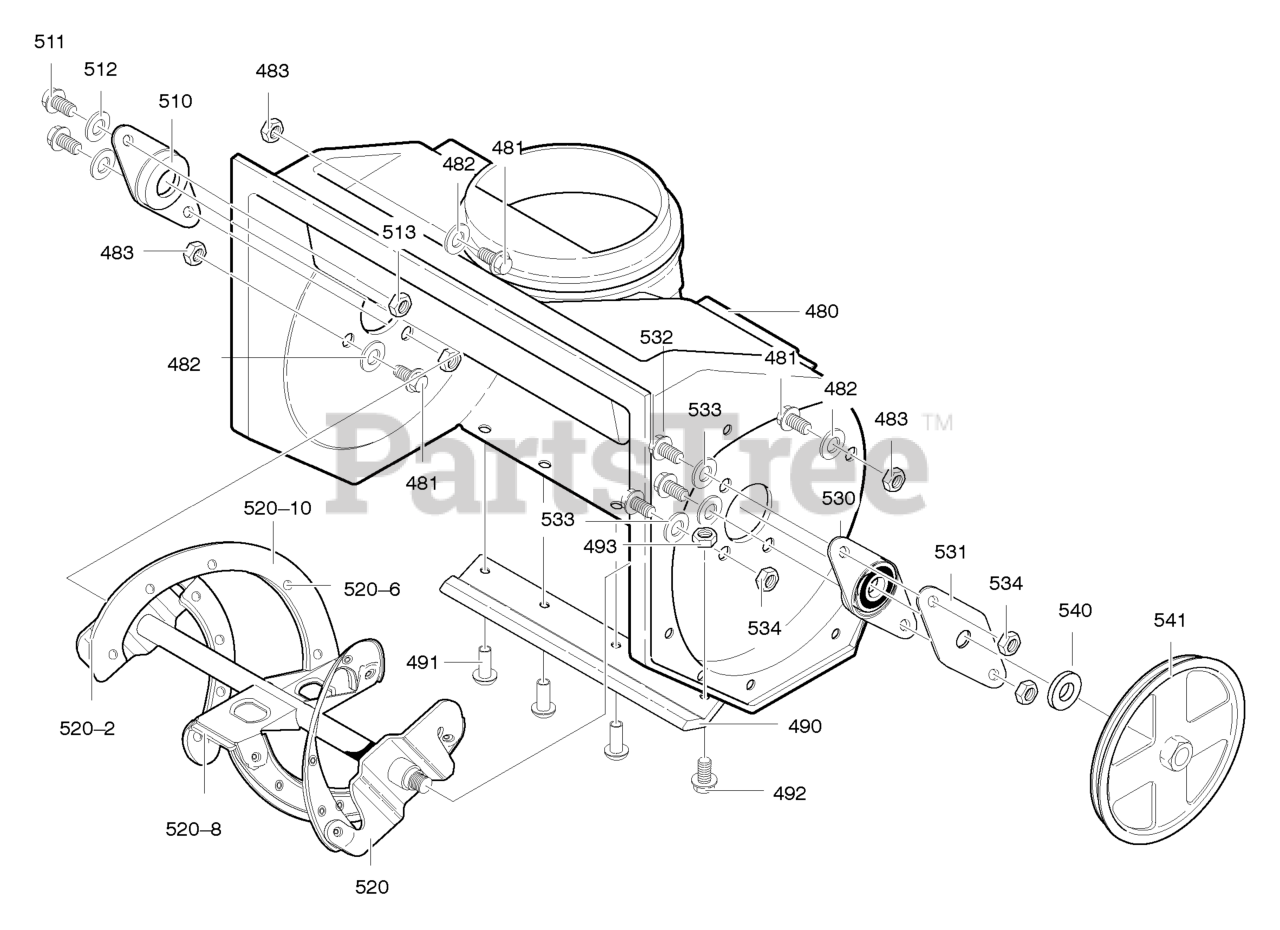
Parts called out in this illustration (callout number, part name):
480	HOUSING, AUGER
481	SCREW, 1/4-20X .75
482	WASHER, FLAT
483	NUT, 1/4-20
490	BLADE, SCRAPER
491	RIVET
492	SCREW, 1/4-20X .75
493	NUT, 1/4-20
510	BRNG, IDX1.25
511	SCREW, 1/4-20X1.
512	WASHER, FLAT
513	NUT, 1/4-20
520	AUGER, ASSY
520-2	BLADE, AUGER
520-6	RIVET
520-8	BLADE, CENTER
520-10	AUGER BLD ASSY
530	BEARING & PLATE
531	PLATE, BEARING
532	SCREW
533	WASHER, FLAT
534	NUT, 1/4-20
